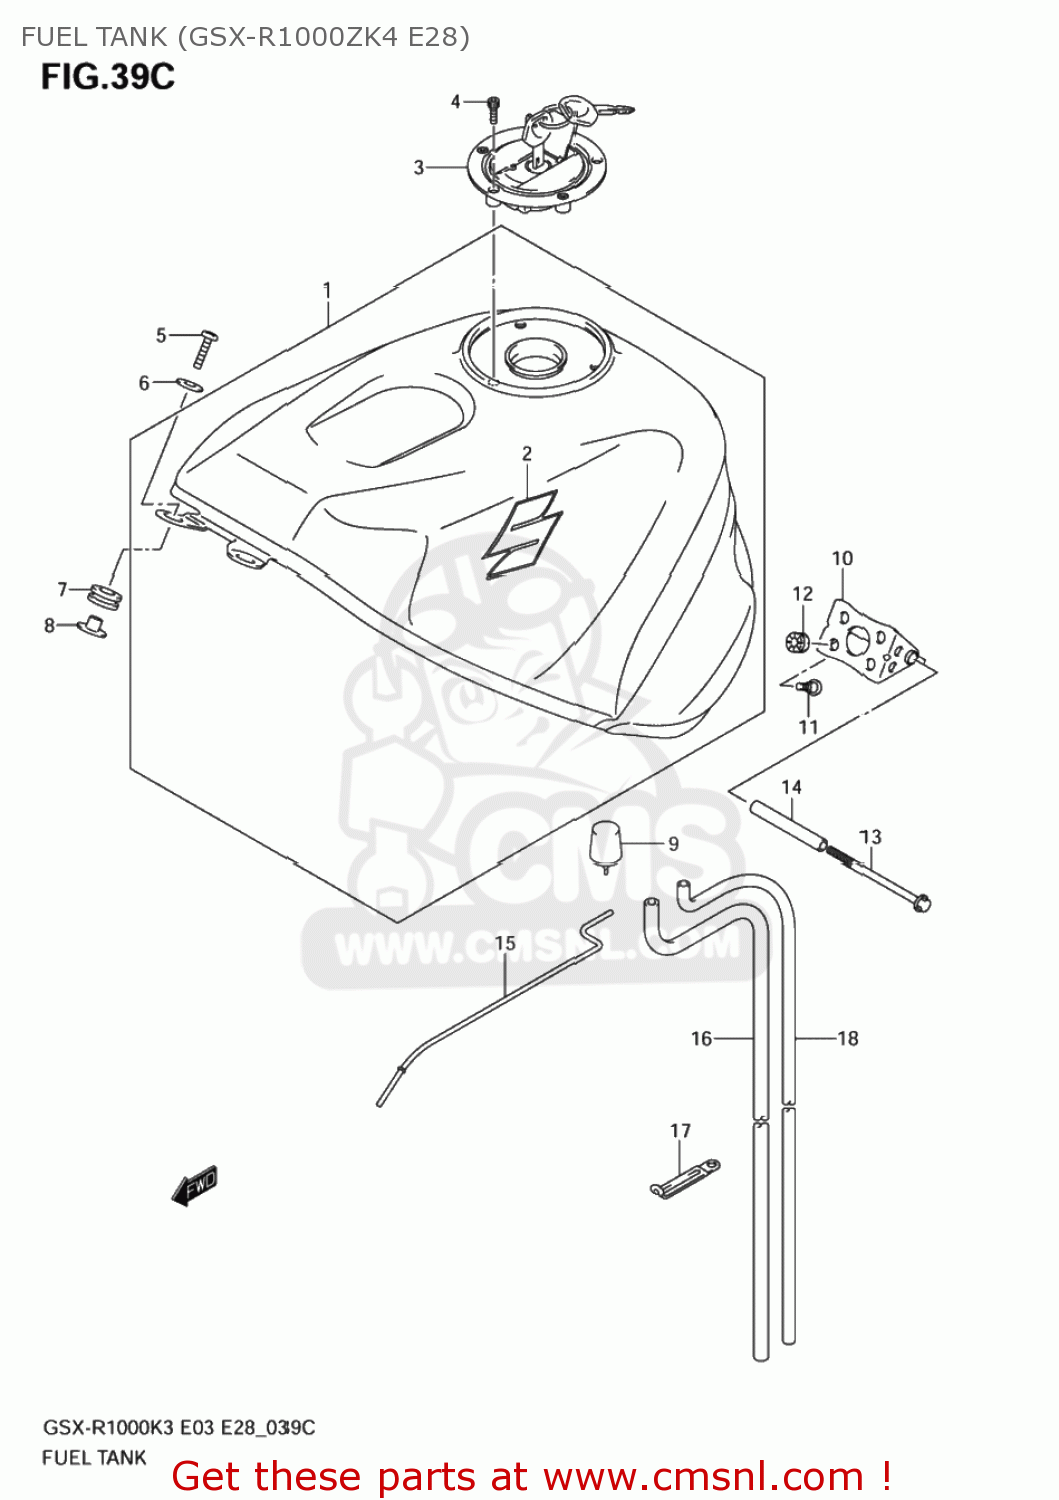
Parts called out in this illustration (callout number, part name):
1	TANK ASSY,FUEL(BLACK)
2	EMBLEM,S
3	CAP SET,FUEL TANK
4	BOLT(5X20)
5	SCREW(6X25)
6	WASHER(6.5X22X1.6)
7	CUSHION,FUEL TANK FR
8	SPACER,FUEL TANK FR
9	CUSHION,FUEL TANK RR
10	BRACKET,FUEL TANK NO.1
11	SCREW,FUEL TAN
12	CUSHION
13	BOLT(6X110)
14	SPACER,FUEL TANK RR
15	STAY,FUEL TANK
16	HOSE,WATER DRAIN
17	CLAMP(L:65)
18	HOSE,FUEL TANK BREATHER
